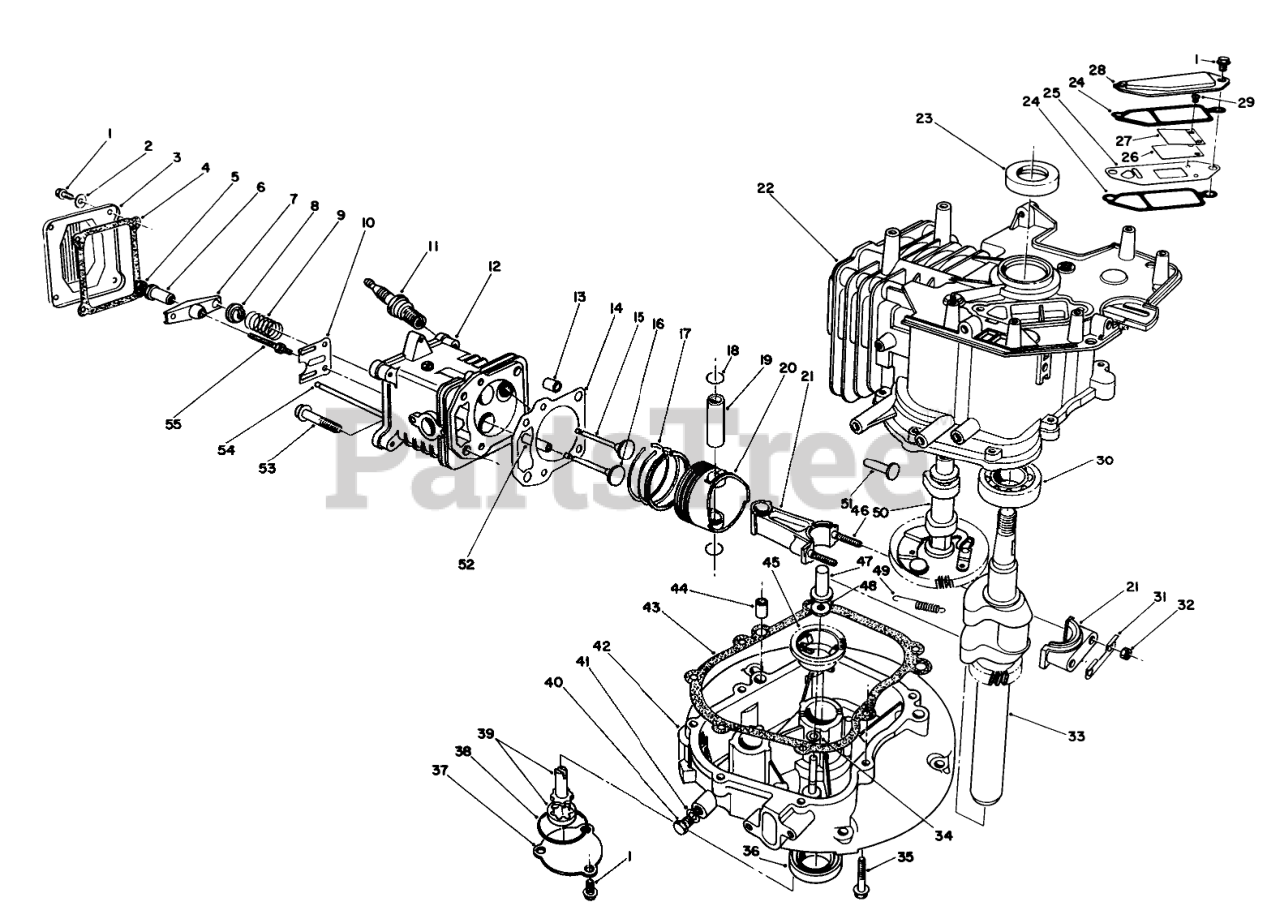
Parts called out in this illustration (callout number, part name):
2	WASHER
3	COVER
4	GASKET
6	PIVOT
8	RETAINER
9	SPRING
10	GUIDE
11	SPARK PLUG
12	Head-Cylinder (Incl. Ref. #52)
14	GASKET
15	VALVE-INTAKE
16	VALVE-EXHAUST
17	RING SET
18	PISTON (OPTIONAL)
20	PISTON
21	Connection Rod Assembly (Incl. Ref. #31, 32, & 46)
22	Block-Engine (Incl. Ref. #23, & 30)
24	GASKET
25	Plate-Breather
26	Valve-Reed
27	Retainer-Reed Valve
28	COVER
29	Screw-Reed Valve
30	BEARING
31	Plate-Lock
33	CRANKSHAFT
34	WASHER
37	COVER
38	O-RING
39	OIL PUMP
40	OIL DRAIN PLUG
41	GASKET
42	Crankcase
43	GASKET
45	GOVERNOR FLYWEIGHT ASM
47	PLUNGER
48	WASHER
49	SPRING
50	Camshaft Assy. (Incl. Ref. #49)
51	TAPPET
52	GUIDE
